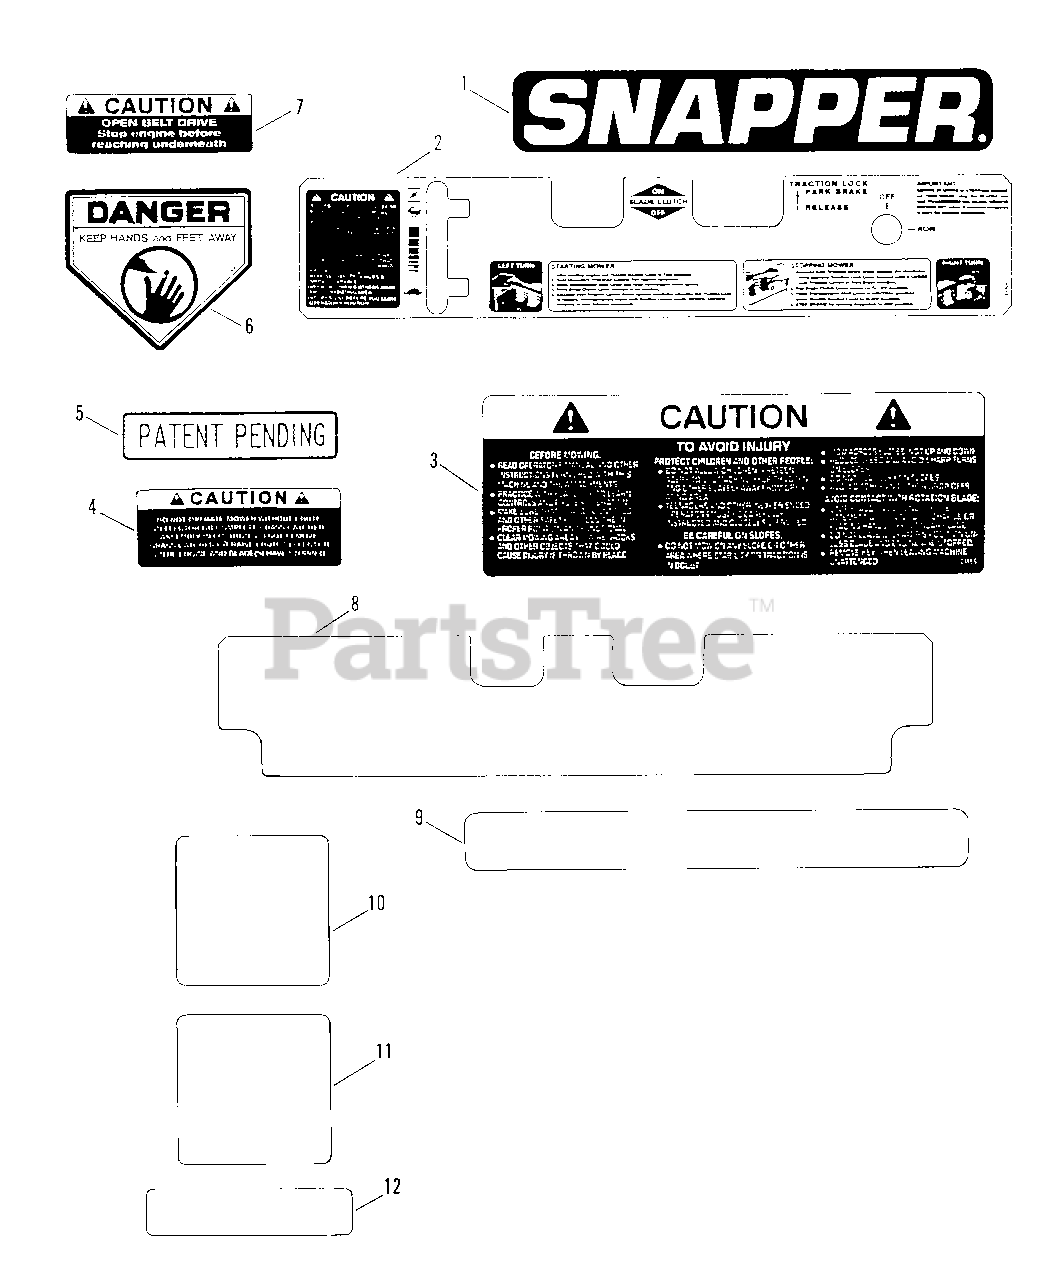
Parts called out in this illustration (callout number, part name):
1	DECAL, SNAPPER
2	DECAL, Console
3	DECAL, Caution
4	DECAL, Caution
5	DECAL, Patent Pending
6	DECAL, Warning
7	DECAL, Caution
8	DECAL, Console
9	DECAL, Pro-Hydro
10	DECAL, Accutrac
11	DECAL, Pro-Hydro
12	DECAL, Blade Engagement
